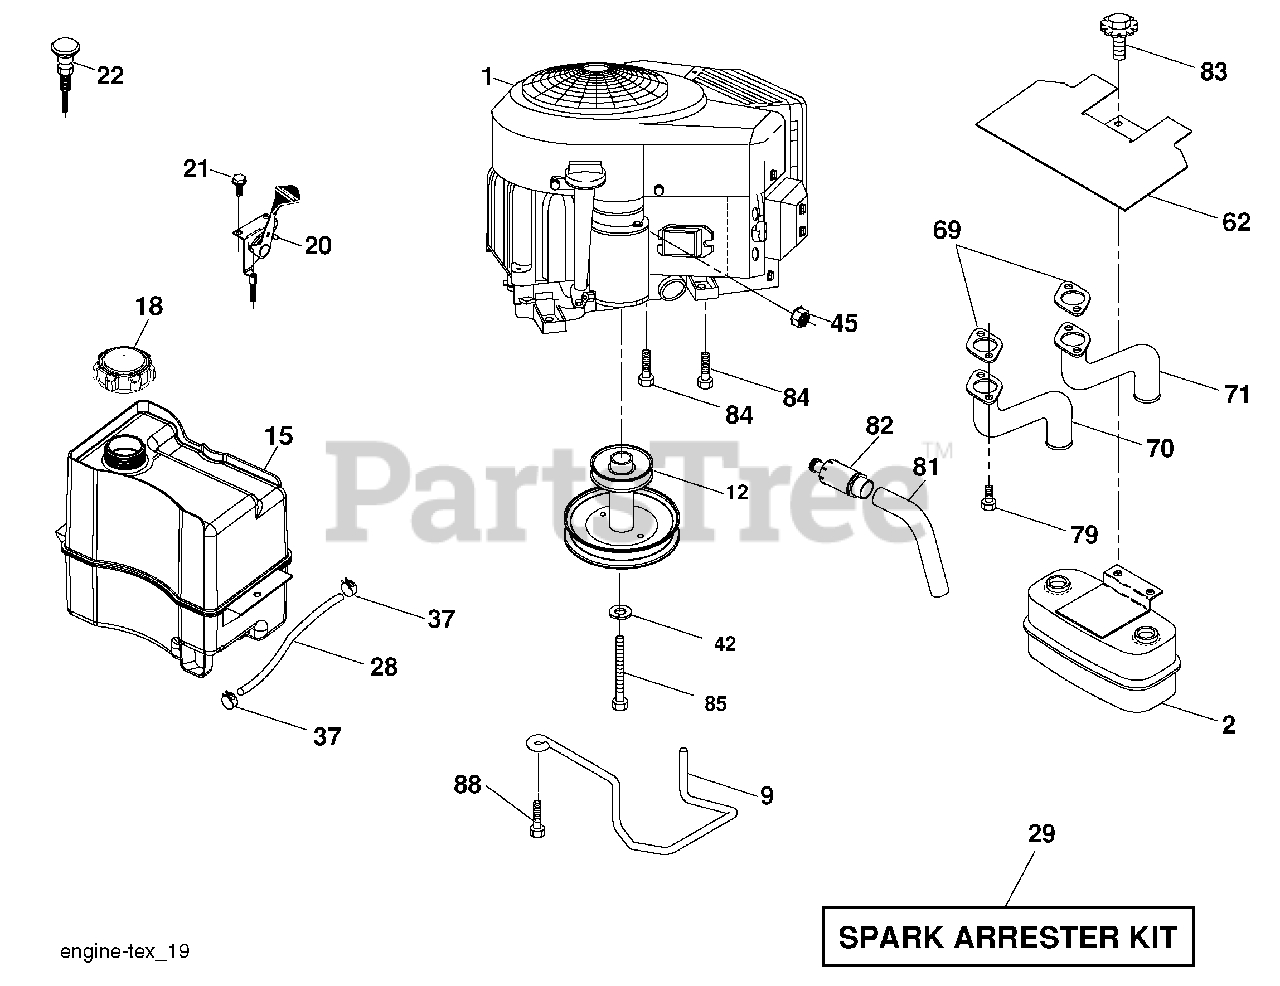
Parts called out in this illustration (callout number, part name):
2	Muffl er
9	Keeper Belt Engine
12	Pulley Engine
15	Tank Fuel
18	Cap Asm
20	Control Throttle
21	Screw 10 x 3/4 Single Lead-Hex
22	Control Choke
28	Fuel Line
29	Spark Arrester Kit
35	Washer Split
37	Clamp Hose
42	Washer Lock 7/16
45	Nut Keps Hex 1/4-20 unc
62	Shield Heat Muffl er
69	Gasket
70	Exhaust Tube LH
71	Exhaust Tube RH
79	Screw Socket Head 5/16-18 x .75
81	Tube Drain Oil Easy
82	Plug Drain Oil
83	Bolt 5/16-18 x 3/4
84	Screw 3/8-16 x 1-1/4
85	Bolt Hex 7/16-20 x 4 x Gr. 5-1.5
88	Screw 3/8-16 x 1
